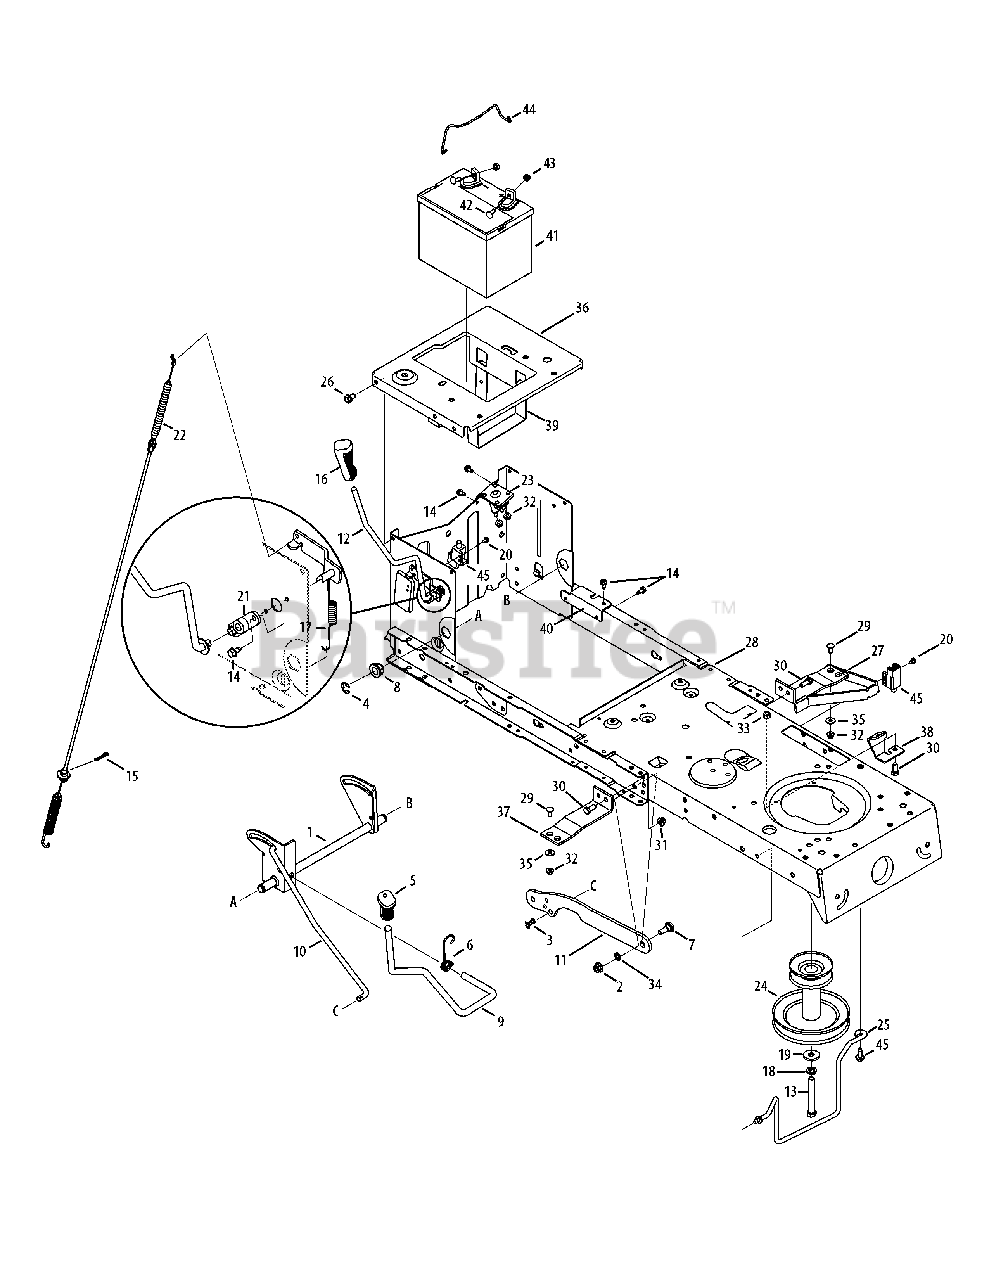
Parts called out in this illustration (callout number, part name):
1	Shaft, Lift
2	Nut, Hex Flange Insert Lock, 3/8-16
3	Bow-Tie Pin, 91, RH
4	E-ring, .625 Shaft
5	Grip, Handle
6	Spring, Lift Handle Torsion
7	Bolt, Shoulder, .500 x .270, 3/8-16
8	Bearing, Hex Flange,
9	Handle, Lift
10	Lift Rod, 13.68
11	Arm, Deck Lift RH
12	PTO Handle Assembly
13	Screw, Hx. Hd., 7/16-20 x 3.25
14	Screw, Hd. Tapp, 1/4-20 x .5
15	Click Pin
16	Handle Grip
17	PTO Spring, Extension
18	Washer, Flat, 7/16
19	Washer, Flat, .450 x .250 x .164
20	Shoulder Screw, #10-32 x .500
21	PTO Bearing
22	Deck Engagement Cable
23	12v. Solenoid
24	Engagement Pulley
25	Belt Keeper Rod Assembly
26	Screw, Hd. Tapp, 5/16-18 x .75
27	Support Bracket Assembly
28	Rider Frame Assembly
29	Carriage Screw, 1/4-20 x .62
30	Screw, Hx. Hd., 5/16-18 x .75
31	Nut, Flange Insert Lock 5/16-18
32	Nut, Hex Flange Insert Lock, 1/4-20
33	Hexlock Nut, 5/16-18
34	Washer, Flat, .385 x .62 x .063
35	Flat Washer, .28 x .74 x .063
36	Seat Bracket Frame
37	Running Board Bracket
38	Frame Support Bracket
39	Battery Bracket
40	Frame Brace Bracket
41	Battery
42	Screw, Shoulder, .250 x .150
43	Nut, Sems, 1/4-20
44	Battery Rod
45	Interlock Switch
